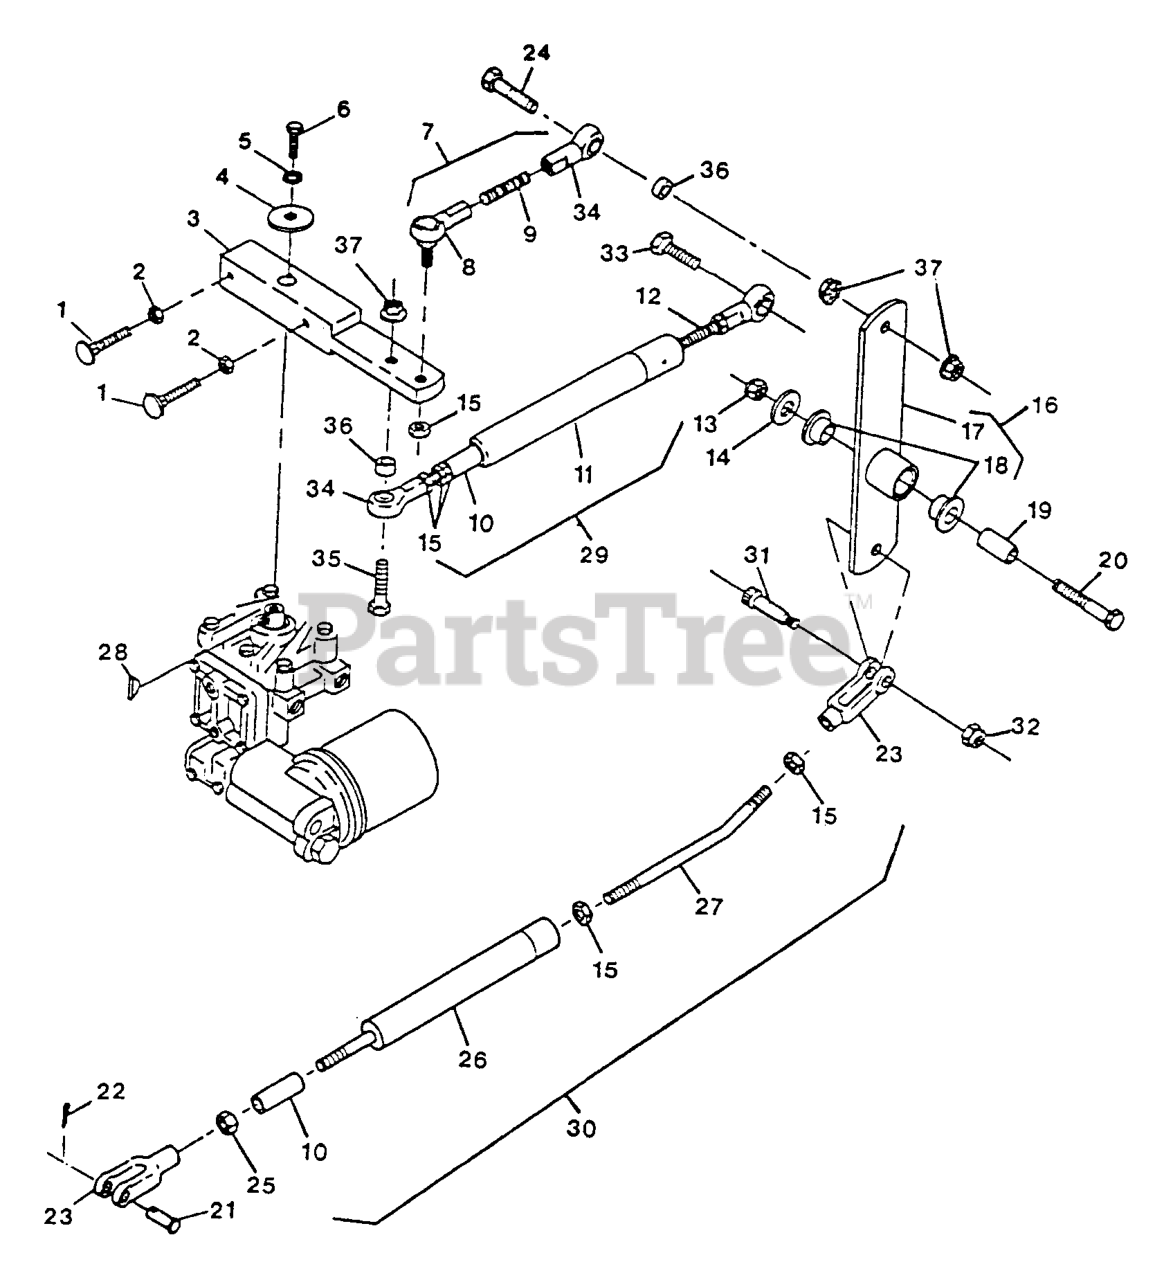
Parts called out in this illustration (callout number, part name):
2	NUT-HEX
3	WLD,ARM TRANSAXLT
4	WASHER-RETAINER, PULLEY
5	WASHER-LOCK
6	Capscrew, 1 /4-20 X 1-1 /2
8	BALLJOINT
9	ROD END PLTD.
10	BUSHING,SPRING GUIDE
12	ROD,END
13	NUT-LOCK, NI
14	WASHER-FLAT
15	NUT-JAM
17	WLD,IDLER LINKAGE
18	BEARING-CONTROL
19	BUSHING,MOTION LEVER
20	SCREW-HH
21	PIN-CLEVIS
22	PIN-COTTER
23	YOKE-ADJUSTABLE
24	SCREW-HH
25	NUT-HEX
27	LINKAGE,ROD
28	KEY-WOODRUFF
30	ASM,PEDAL OVERRIDE
31	SCREW-HSH
32	NUT-LOCK, NI
33	SCREW-HH
34	BALLJOINT-RH
35	SCREW-HH
36	SPACER-PLATED
